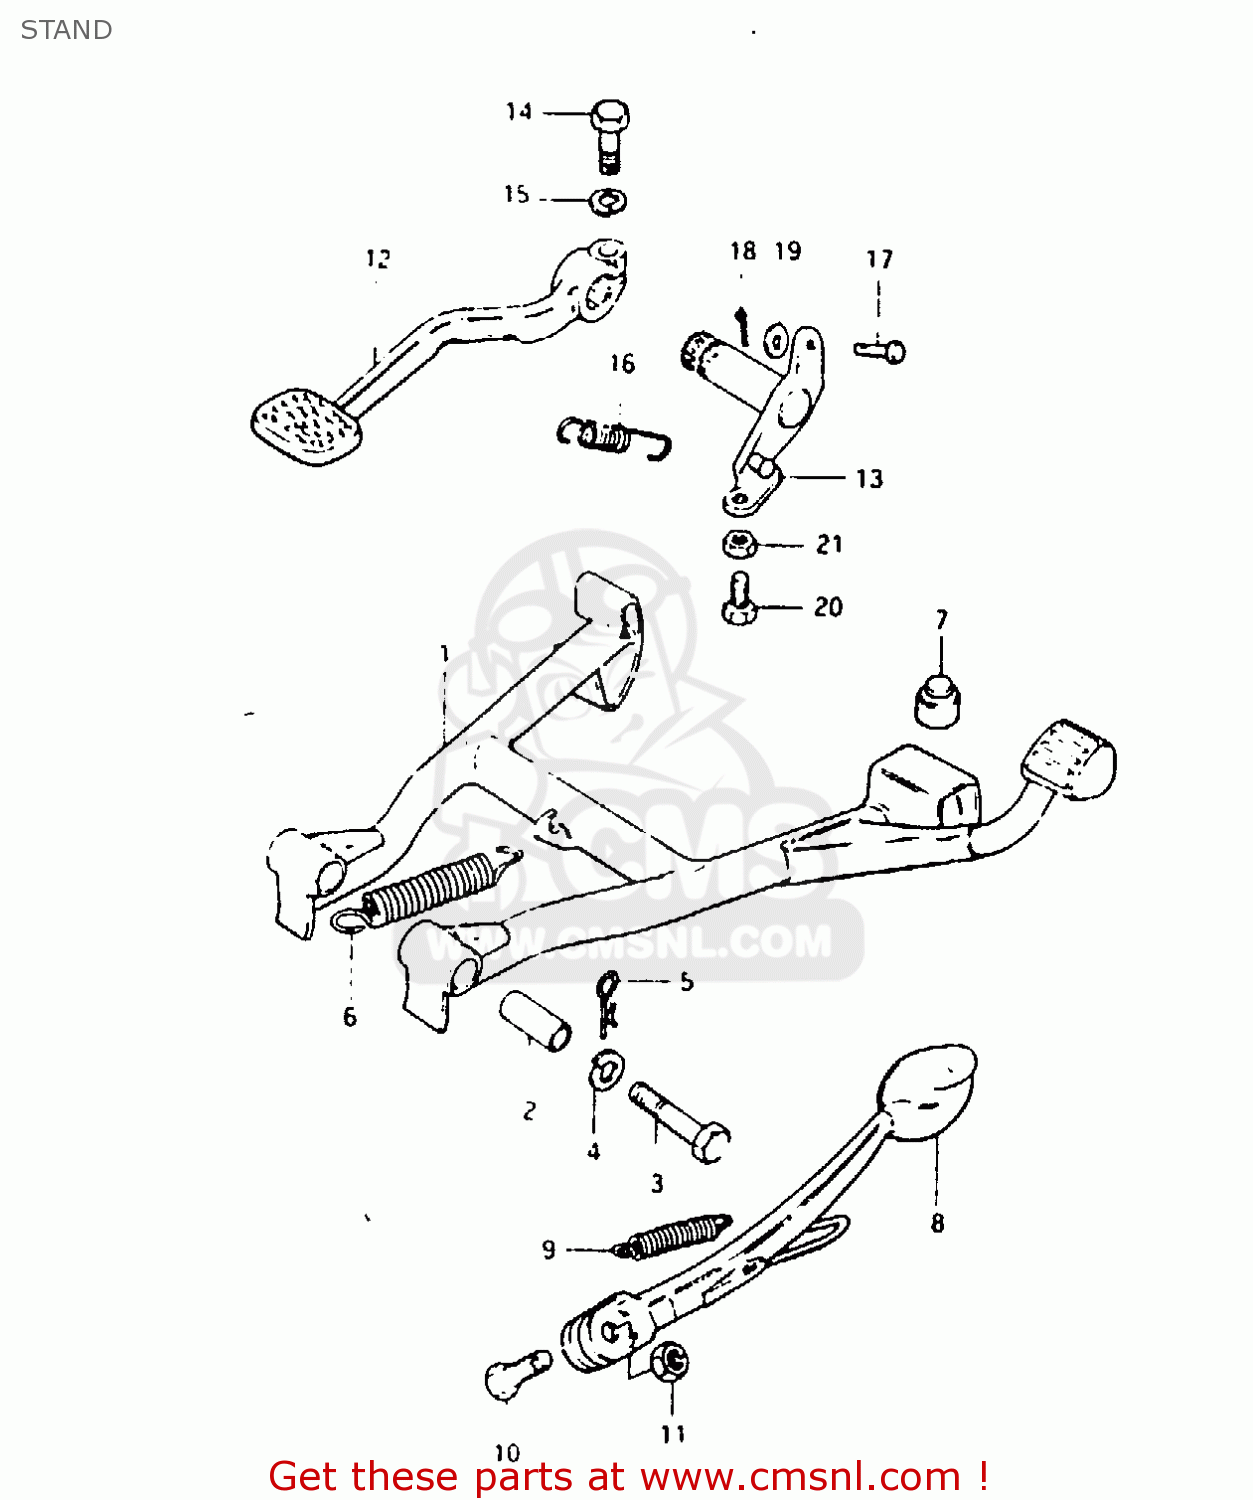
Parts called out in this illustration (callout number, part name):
1	STAND,CENTER
2	SPACER(10X16X38.8)
3	BOLT
4	LOCK WASHER
5	CLIP
6	SPRING
7	CUSHION
8	STAND,PROP
9	SPRING
10	BOLT(10X30)
11	NUT
12	PEDAL, BRAKE
13	ARM,BRAKE PEDAL
14	BOLT
15	LOCK WASHER
16	SPRING
17	PIN
18	PIN
19	WASHER
20	BOLT
21	NUT
